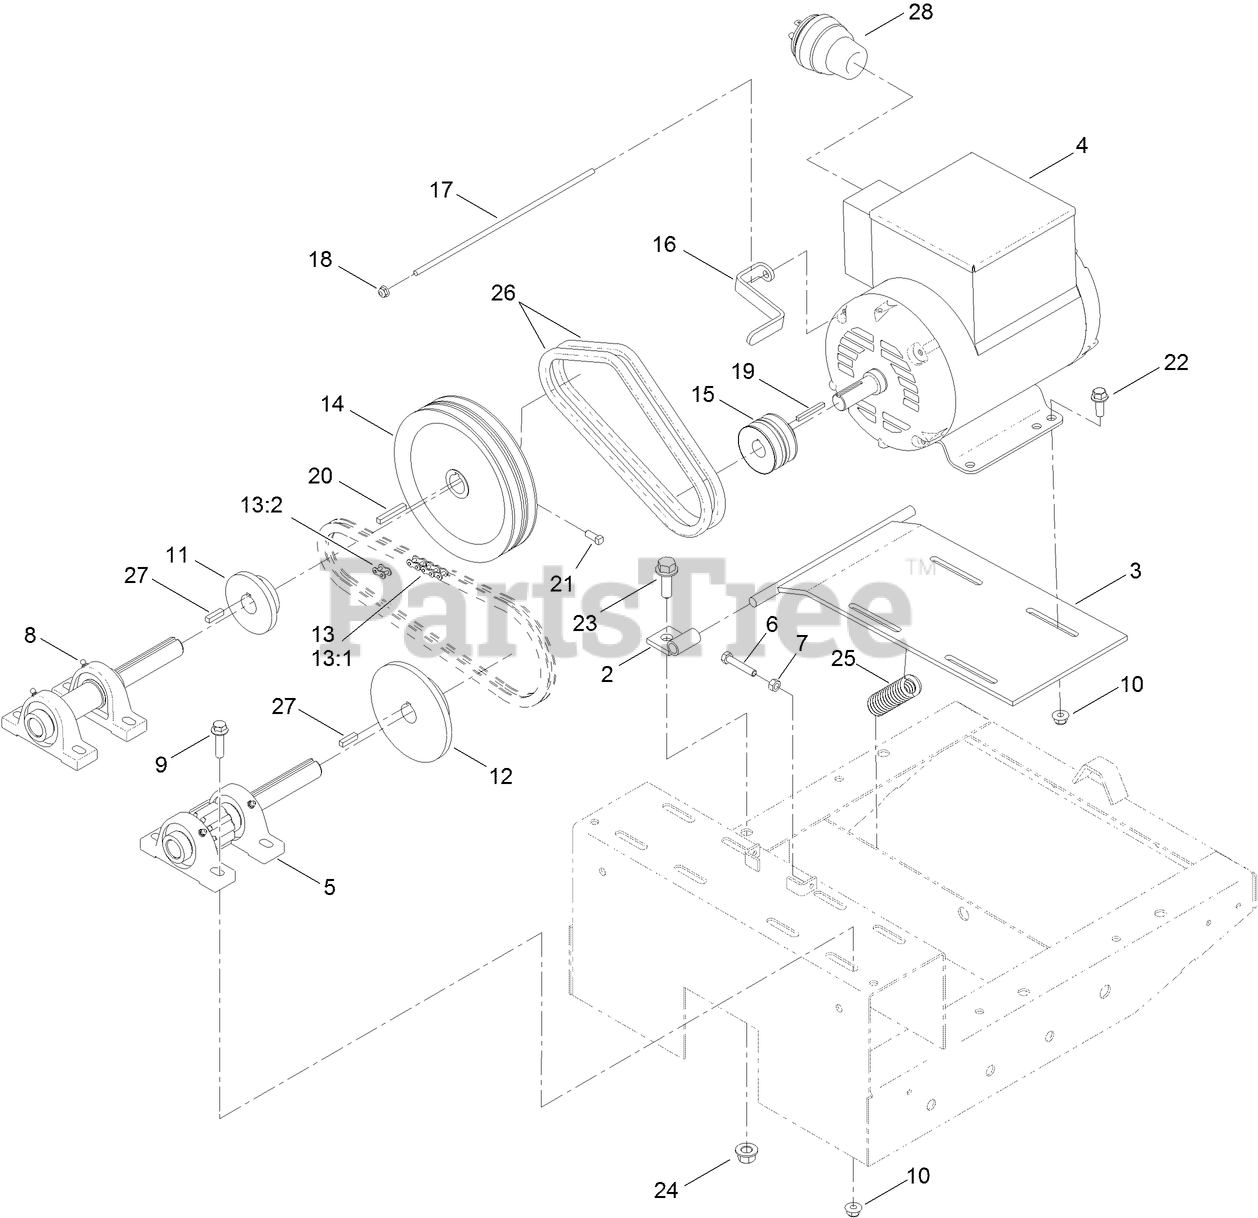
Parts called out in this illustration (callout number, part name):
2	MOUNT-MOTOR
3	BASE-MOTOR
4	MOTOR-ELECTRIC
5	PINION ASM
6	SCREW-HH
7	NUT-HEX
8	IDLER ASM
9	SCREW-HHF
10	NUT-HF, NI
11	SPROCKET
12	SPROCKET
13	CHAIN SET
13:1	CHAIN
13:2	LINK-CONNECTING, NO. 50
14	SHEAVE
15	SHEAVE
16	GUIDE-BELT
17	ROD-THREADED
18	NUT-HF
19	KEY-SQUARE
20	KEY-SQUARE
21	SCREW-SET, SQH
22	SCREW-HHF
23	SCREW-HHF
24	NUT-LOCK
25	SPRING
26	BELT-V
